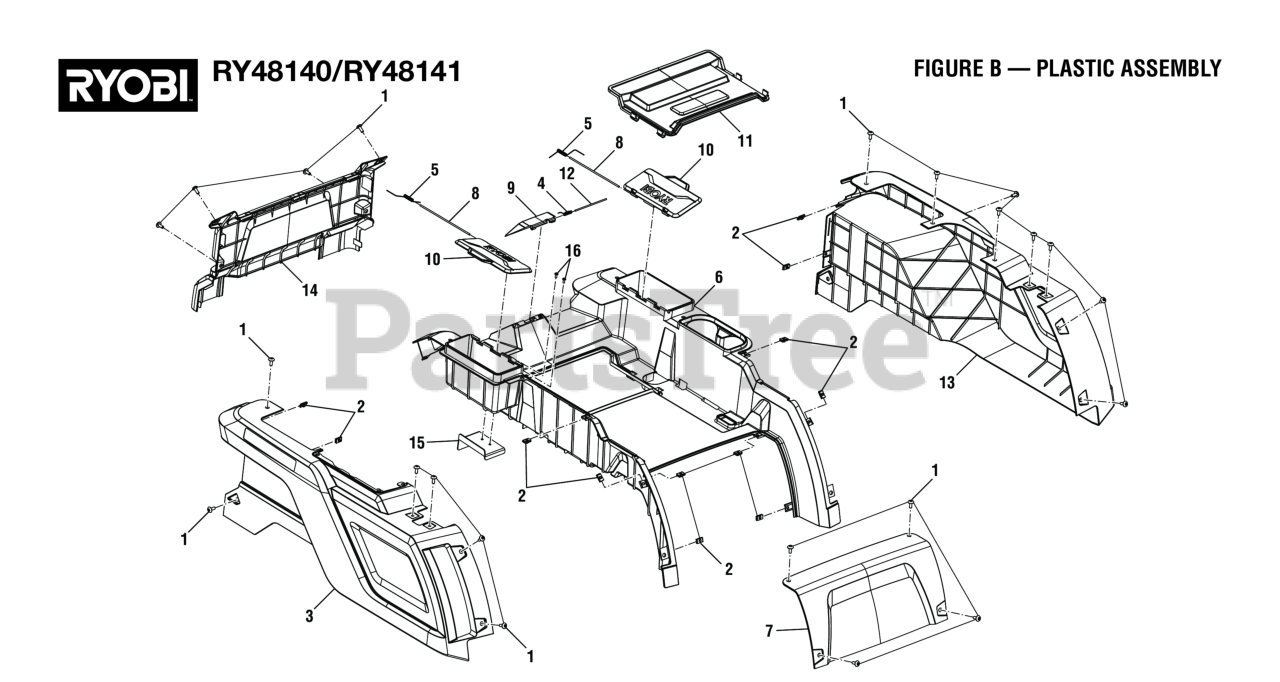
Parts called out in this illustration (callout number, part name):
1	Screw (M6 x 10 mm, Soc. Button Hd.)
2	Clip-On Nut (M6)
3	Right Trim Cover
4	Charger Port Door Spring
5	Storage Box Spring
6	Center Trim Cover
7	Front Access Panel
8	Storage Box Hinge Pin
9	Charger Port Door
10	Storage Box Lid
11	Center Access Panel
12	Charger Port Door Hinge Pin
13	Left Trim Cover
14	Rear Trim Cover
15	Main Relay Guard
16	Screw (M4 x 10 mm, Pan Hd.)
